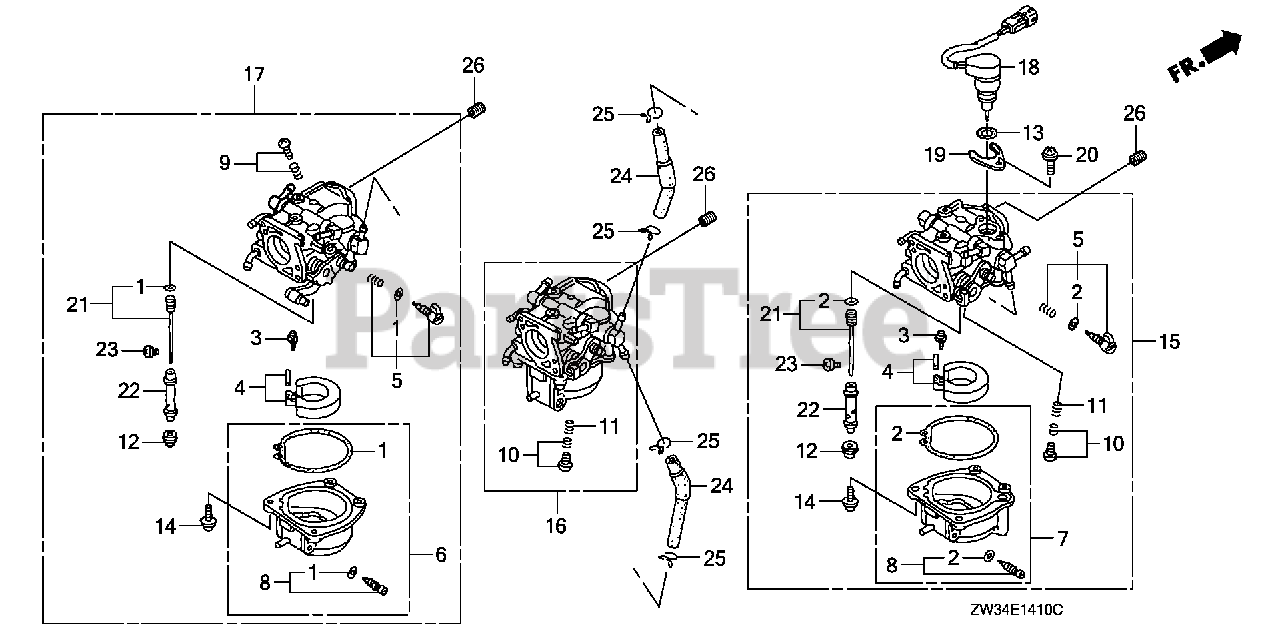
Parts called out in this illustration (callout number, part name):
1	GASKET SET
2	GASKET SET
3	VALVE SET, FLOAT
4	FLOAT SET
5	SCREW SET (CARBURETOR NO.)
6	CHAMBER SET, FLOAT
7	CHAMBER SET, FLOAT (CARBURETOR NO.)
8	SCREW SET, DRAIN (CARBURETOR NO.)
11	SPRING, COMPRESSION COIL
12	SCREW, PLUG
13	O-RING, BYSTARTER
14	SCREW-WASHER
15	CARBURETOR ASSY. (#1) (CARBURETOR NO.)
16	CARBURETOR ASSY. (#2) (CARBURETOR NO.)
17	CARBURETOR ASSY. (#3) (CARBURETOR NO.)
18	BYSTARTER ASSY., AUTO (CARBURETOR NO.)
19	PLATE, SETTING
20	SCREW-WASHER
21	JET SET (#45) (CARBURETOR NO.)
22	NOZZLE, MAIN (CARBURETOR NO.)
23	JET, MAIN (#130)
23	JET, MAIN (#132)
23	JET, MAIN (#135) (CARBURETOR NO.)
23	JET, MAIN (#120) (CARBURETOR NO.)
23	JET, MAIN (#122)
23	JET, MAIN (#125)
24	TUBE (CARBURETOR NO.)
25	CLIP, TUBE (B12)
26	SCREW, PLUG (CARBURETOR NO.)
